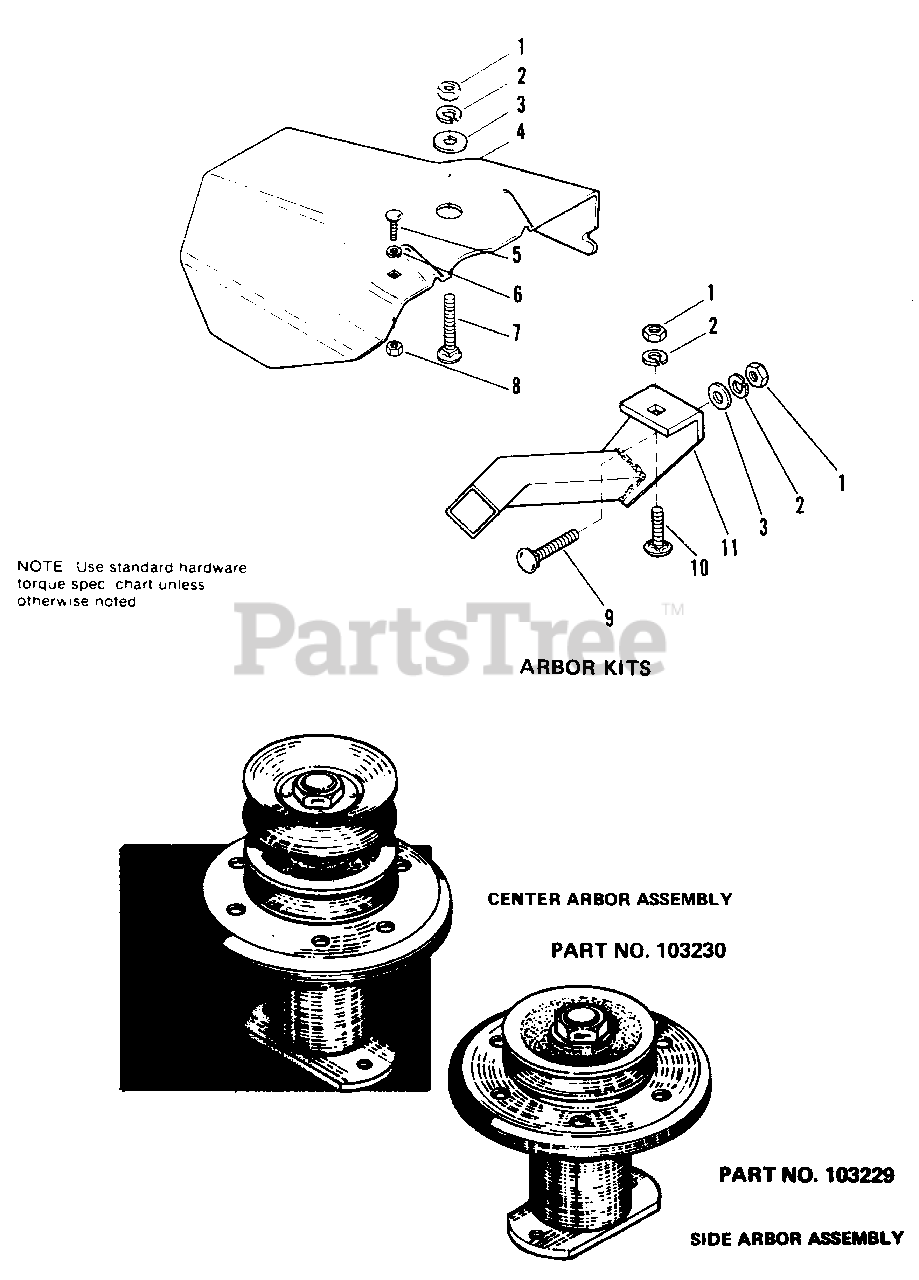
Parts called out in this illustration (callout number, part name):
1	NUT, Hex, Full, 3/8-16
2	LOCKWASHER, 3/8
3	WASHER
4	DEFLECTOR
5	CAPSCREW, Hex Hd., 5/16-18 x 1-1/4
6	LOCKWASHER, 5/16
7	BOLT, Carriage. 5/16-18 x 1-1/4
8	NUT, Retainer, 5/16-18
9	BOLT, Carriage. 3/8-16 x 1-1/4
10	BOLT, Carriage. 3/8-16 x 1
11	GUARD ASSY., Stone
